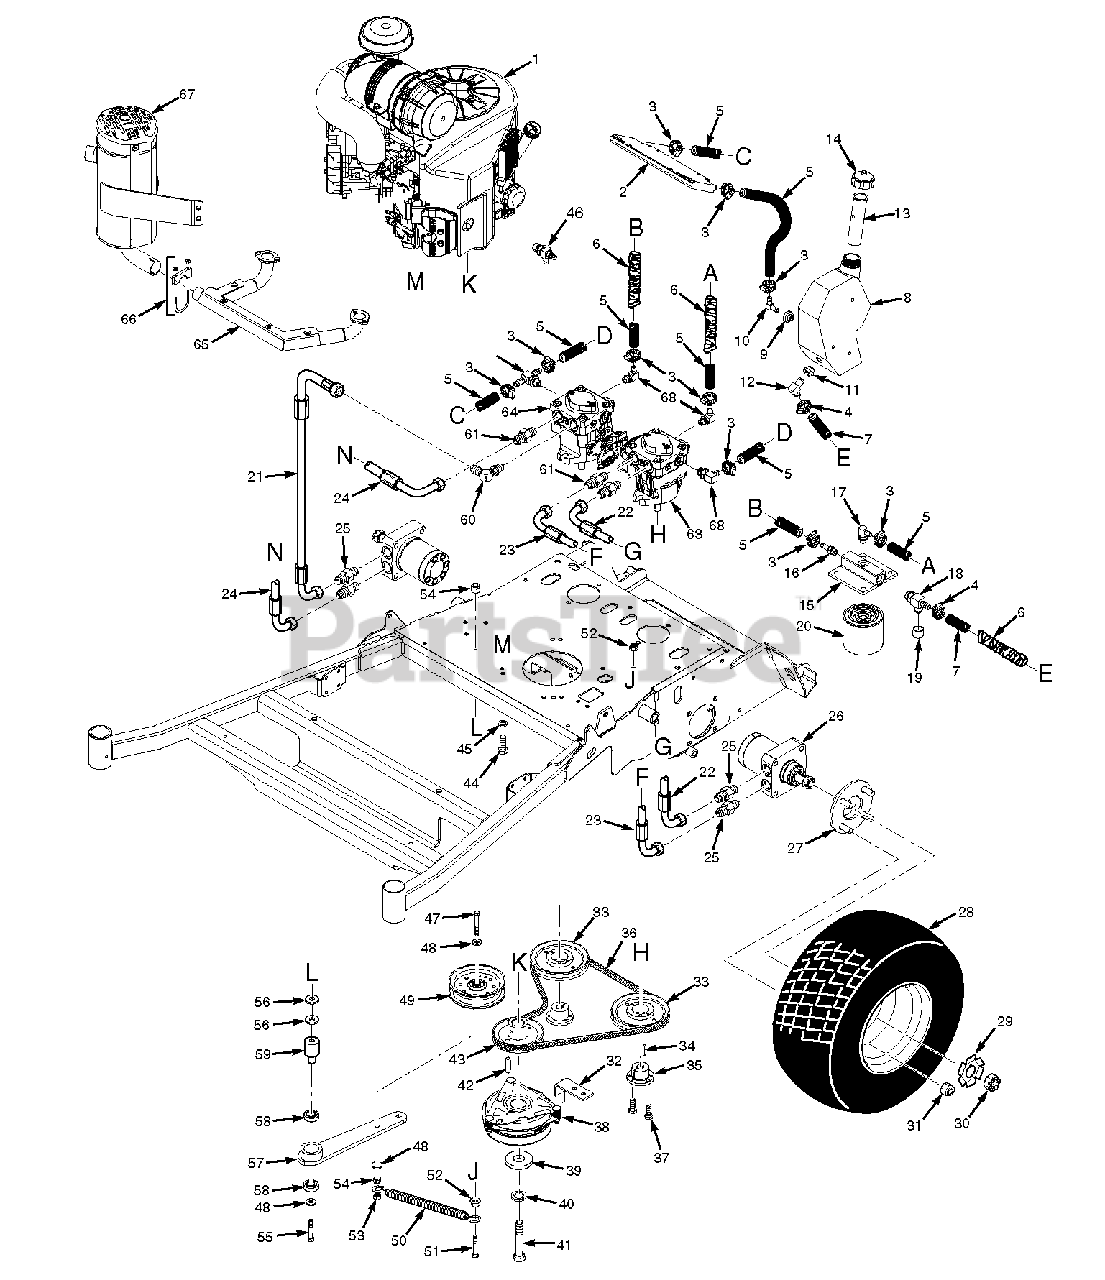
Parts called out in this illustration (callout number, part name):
1	Engine, 29hp Kawasaki FX
2	Cooler, Transmission
3	Clamp, .69 Max Dia.
4	Clamp, .87 Max Dia.
5	Hose, 3/8 Pushlock
6	Heatshield, Flexible
7	Hose, 1/2 Pushlock
8	Hydraulic Tank Assy.
9	Bushing, .56 Dia, Viton
10	Fitting, 90 Degree - .38 Hose
11	Bushing, .78 Dia. Viton
12	Fitting, 90 Degree - .50 Hose
13	Insert, Filler Neck
14	Cap, Hydraulic Tank
15	Filter Head
16	Fitting
17	Elbow, 90 Degree
18	Tee Fitting, 3/4 O-Ring
19	Cap, 3/4" JIC
20	Oil Filter
21	Hose Assembly
22	Hose Assembly
23	Hose Assembly
24	Hose Assembly
25	Fitting, Union 1/2 x 5/8
26	Wheel Motor
27	Wheel Hub
28	Wheel Assembly
29	Lockwasher, Wheel Motor
30	Hex Castle Nut, 3/4-28
31	Wheel Nut
32	Anti-Rotation Bracket
33	Pulley, 5.45 OD - Tapered Bore
34	Key, 5 x 5 x 25mm
35	Tapered Hub, 15mm Bore
36	Belt, Pump Drive
37	Bolt, Hex Head 1/4-20 x 1" Gr. 8
38	Clutch w/Tag
39	Flatwasher, 7/16-.469 x 1.75 x .25
40	Lockwasher, 7/16" Spring
41	Bolt, Hex Head 7/16-20 x 2-1/4" Patch
42	Key, 1/4 x 1/4 x 3-1/2"
43	Pulley, 4.75 OD - 1.125" Bore
44	Bolt, Hex Head 3/8-16 x 1-1/4"
45	Lockwasher, 3/8" Spring
46	Oil Drain
47	Bolt, Hex Head 3/8-16 x 2-3/4"
48	Flatwasher, 3/8-.391 x .938 x .105 HD
49	Pulley, 4-1/2" Idler
50	Spring, Transmission
51	Bolt, Hex Head 3/8-16 x 3"
52	Nut, Serrated Flange 3/8-16
53	Nut, Center Lock 3/8-16
54	Nut, Elastic Stop 3/8-16
55	Bolt, Hex Head 3/8-16 x 3-1/4"
56	Flatwasher, 3/8-.375 x 1-1/2 x .059
57	Idler Arm Assy
58	Bearing
59	Idler Pivot, Long
60	Elbow, 90 Degree - 1/2 x 1/2
61	Fitting, Union 1/2 x 1/2
62	Tubing, Oil Drain
63	Pump, LH - 12cc
64	Pump, RH - 12cc
65	Exhaust Manifold
66	Clamp, Muffler 1.25 Dia.
67	Muffler
68	Elbow, 90 Degree
